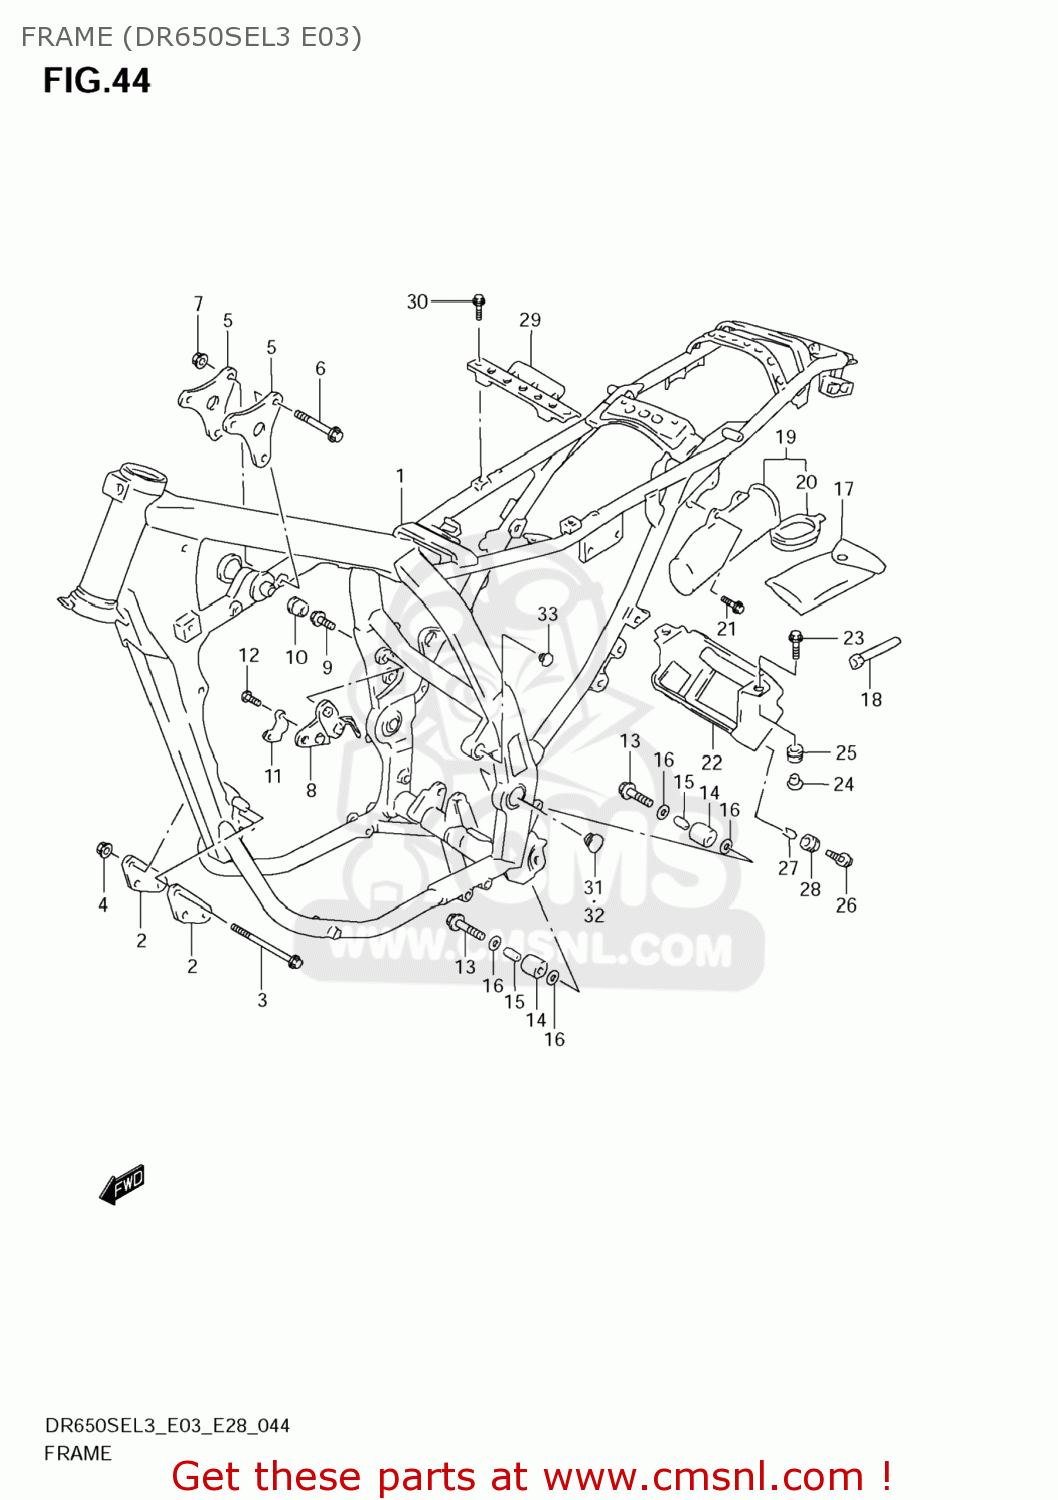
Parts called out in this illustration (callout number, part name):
1	FRAME(GRAY)
2	PLATE,ENG MTG FR
3	BOLT(8X100)
4	NUT
5	PLATE,ENG MTG UPR
6	BOLT(8X55)
7	NUT
8	PLATE,ENG MTG RR,R
9	BOLT
10	PLUG(OD:22)
11	BRACKET,STOP SWITCH
12	SCREW
13	BOLT(8X38)
14	ROLLER,CHAIN CONTROL UPR
15	SPACER(8.6X12X25.5)
16	WASHER
17	TOOL ASSY
18	SPARK PLUG WRENCH(16)
19	HOLDER,TOOL
20	CAP,HOLDER
21	BOLT(6X16)
22	HOLDER,BATTERY
23	BOLT(6X20)
24	WASHER
25	CUSHION
26	BOLT(6X16)
27	SPACER(6.1X9X7.5)
28	CUSHION
29	PLATE,BATTERY FITING
30	BOLT
31	PLUG,FRAME PIVOR,R
32	PLUG,FRAME PIVOR,L
33	PLUG,FRAME BOSS
